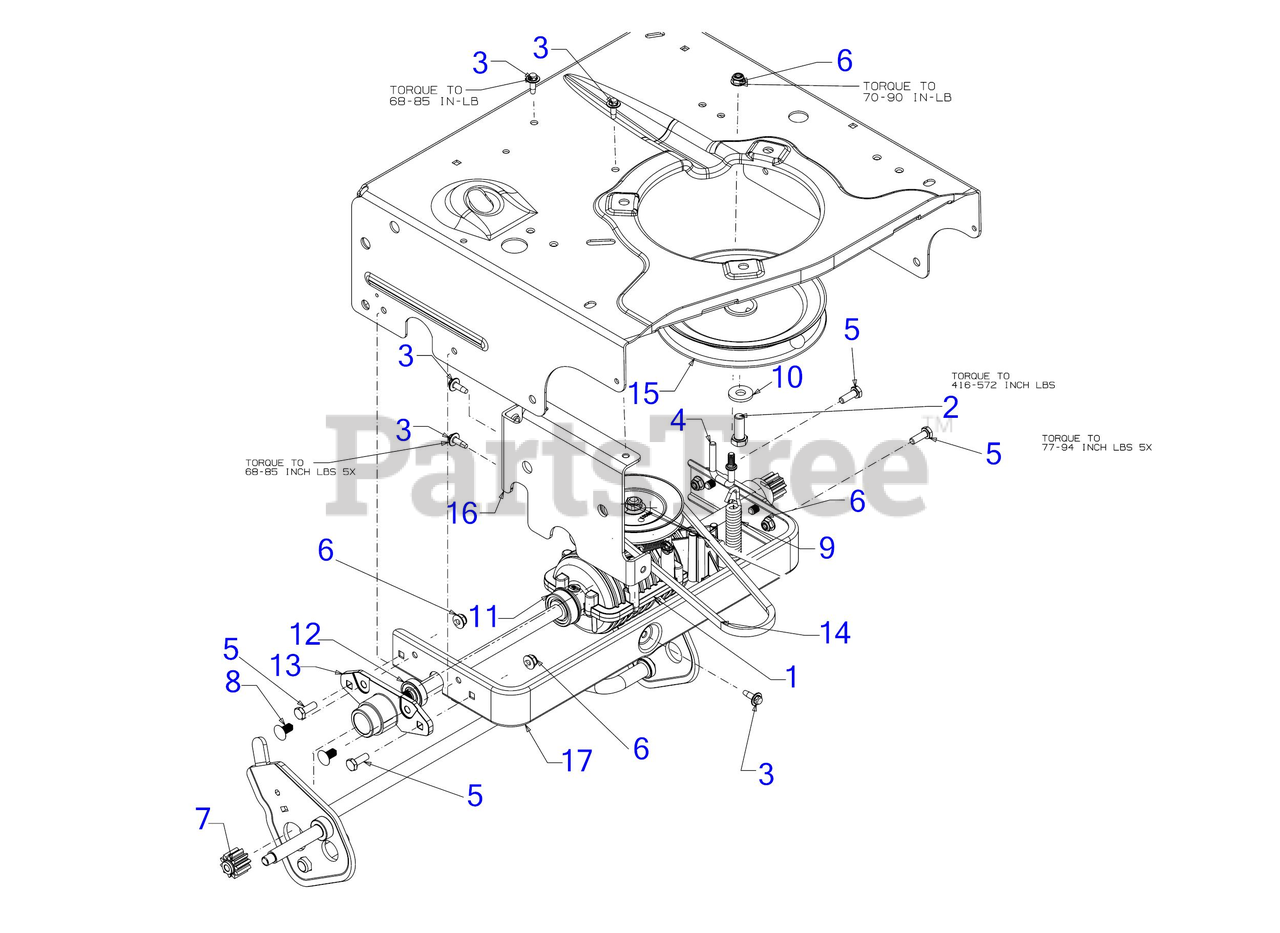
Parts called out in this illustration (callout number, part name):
1	TRANSMISSION
2	SCREW 3/8-24 x 1.00 GR5
3	SCREW M6-1 x .625
4	EYE BOLT SPRING GUIDE 1/4-20
5	SCREW 1/4-20X.75 GR5
6	FLANGE LOCK NUT
7	SPUR GEAR 10T
8	RETAINER PAN CLIP
9	EXTENSION SPRING
11	ROLLER BEARING
12	BALL BEARING
13	DRIVE BEARING
14	BELT 3/8 x 24.68"
15	ENGINE PULLEY
16	TRANSMISSION SUPPORT BRACKET
17	AXLE BEARING SUPPORT PLATE
